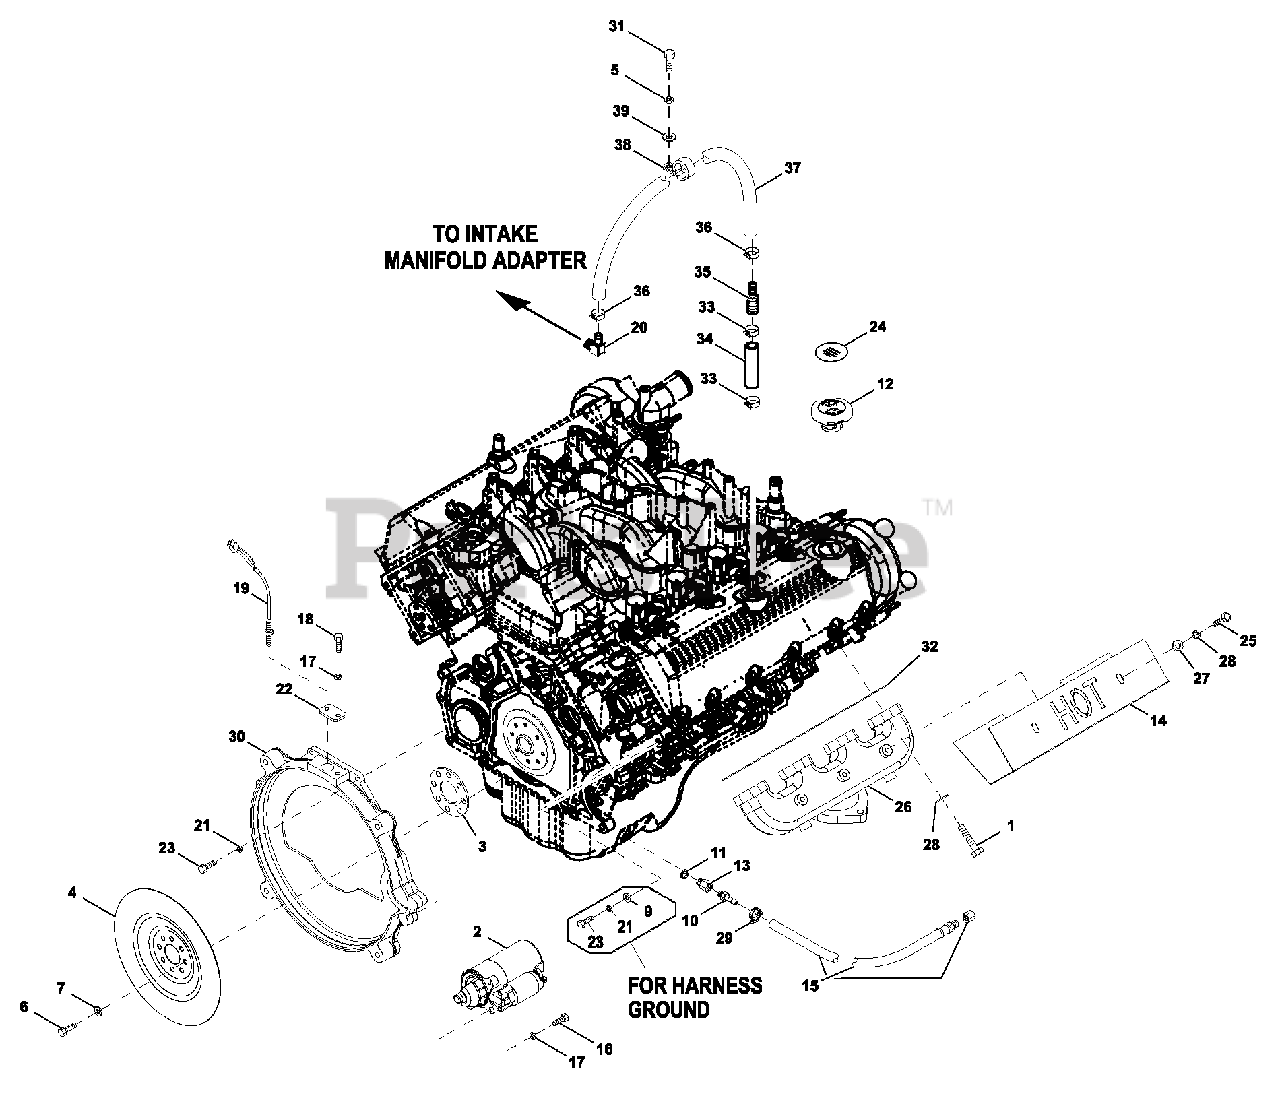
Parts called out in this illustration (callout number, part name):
1	SCREW SHC M8-1.25 X 35 SS
2	STARTER MOTOR 12V
3	SPACER FLEXPLATE 5.4L/6.8L (1800 RPM ONLY)
4	FLEX PLATE 2 POLE 5.4L/6.8L (1800 RPM UNITS ONLY)
5	WASHER LOCK M6-1/4
6	SCREW HHC M10-1.0X 25 G10.9
7	WASHER FLAT M10 HEAVY DUTY
9	WASHER FLAT 3/8-M10 ZINC
10	BARBED STR 3/8 NPTX 3/8
11	WASHER NYLON .565
12	CAP, OIL FILLER
13	ADAPTER M14-1.50X3/8NPTA
14	HEAT SHLD EXHAUST MANIFOLD
15	HOSE OIL DRAIN ASSY 16"
16	SCREW SHC M8-1.25 X 30 G12.9
17	WASHER LOCK M8-5/16
18	SCREW HHC M8-1.25X20 G8.8
19	ASSY MAGPICKUP (3/8-24 MALE)
20	BARBED EL 90 1/4NPTX 3/8
21	WASHER LOCK M10
22	PLATE MAG PICK-UP ADAPTOR
23	SCREW SHC M10-1.5X55G12.9
24	DECAL REFER TO OWNERS MANUAL
25	SCREW HHC 5/16-18 X 1/2 SSTL
26	MACHINED MANIFOLD EXHAUST 5.4L
27	WASHER FLAT M8 SS
28	WASHER LOCK M8 SSTL
29	CLAMP HOSE .38- 87
30	ENGINE ADAPTER 5.4L/6.8L
31	SCREW HHC M6-1.0 X 16 C8.8
32	GASKET, EXHAUST MANIFOLD
33	CLAMP HOSE BAND .88"
34	HOSE COOL 5/8"ID 250+WP (2" LG)
35	HOSE BARB REDUCER 5/8"-3/8"ID
36	CLAMP HOSE BAND .63
37	HOSE 3/8 ID SINGLE BRAID (15" LG)
38	CLAMPSTL/VNL .7 5X .3 4 3Z
39	WASHER FLAT 1/4-M6 ZINC
